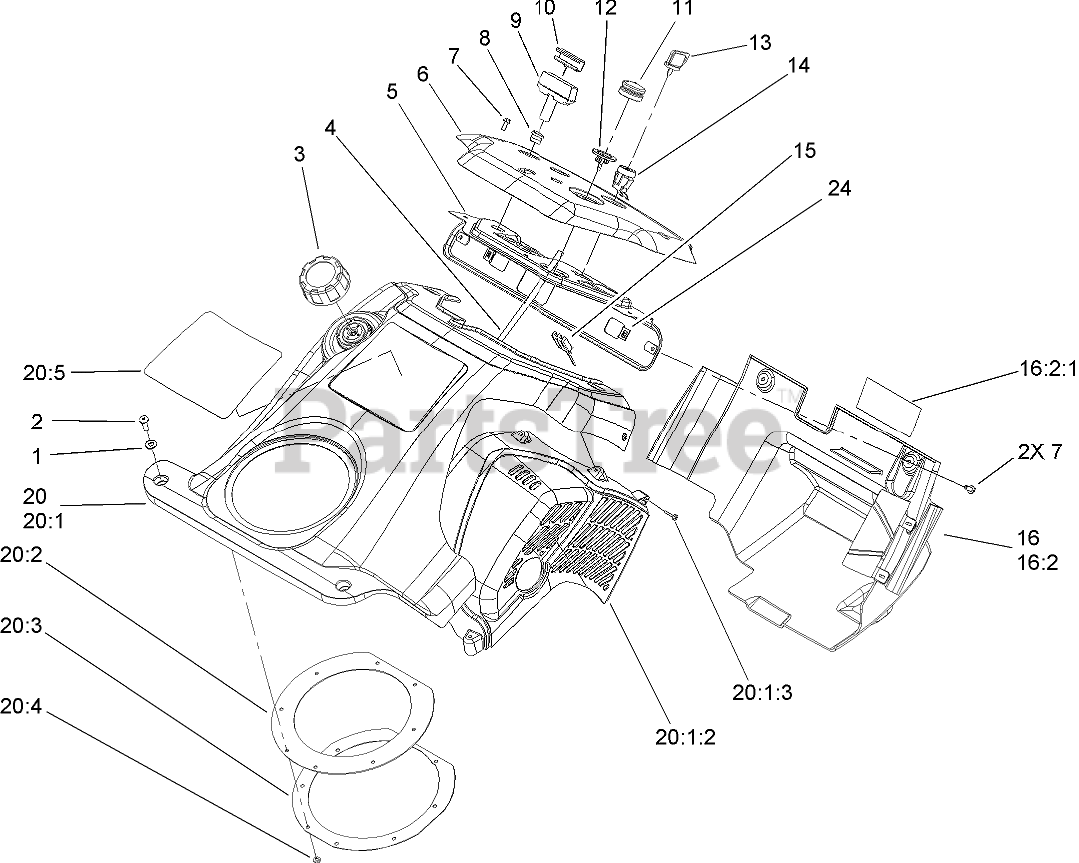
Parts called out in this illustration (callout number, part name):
1	WASHER-FLAT
2	SCREW-PPH
3	GAS CAP ASM
4	HOSE-PRIMER
5	PANEL-SUPPORT, CONTROL
6	PANEL-CONTROL
7	SCREW-HWH
8	GUIDE-ROPE, STARTER
9	HANDLE-START
10	CLIP-STARTER
11	BULB-PRIMER
12	BODY-PRIMER
13	KEY-IGNITION
14	SWITCH
15	CONNECTOR-BODY
16	LOWER SHROUD AND BAFFLE ASM
16:2	SHROUD-LOWER
16:2:1	DECAL
20	UPPER SHROUD ASM
20:1	SHROUD-UPPER
20:1:2	SHIELD-HEAT
20:1:3	SCREW-PPH
20:2	Seal-Chute
20:3	RETAINER-SEAL, CHUTE
20:4	PALNUT
20:5	DECAL-SHROUD, UPPER
24	NUT-SPEED
